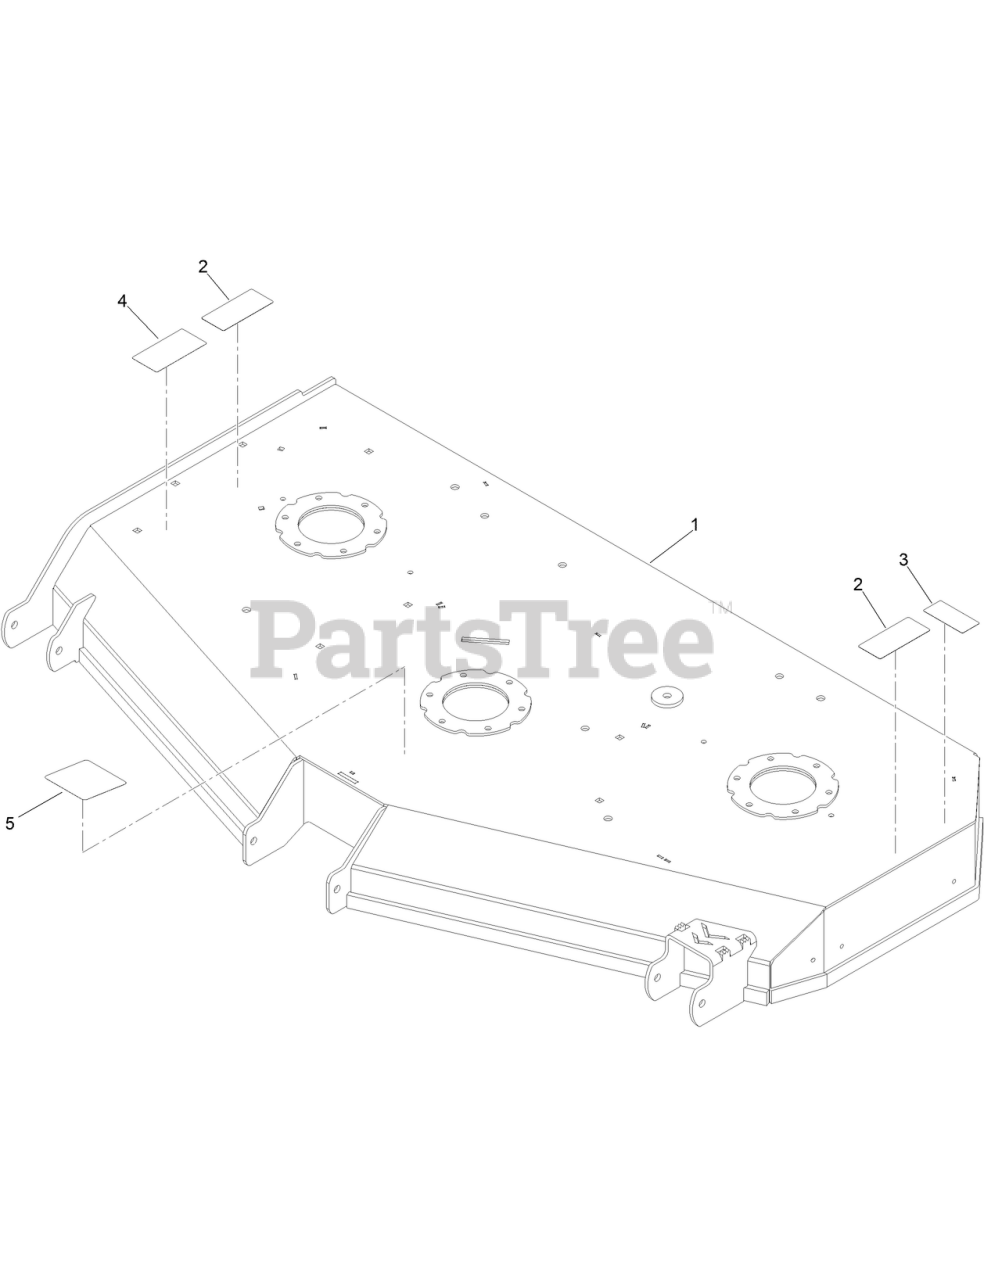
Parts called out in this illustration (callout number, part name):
1	DECK ASM-61 PAINTED BLACK
2	DECAL-ROTATING FAN HAZARD
3	DECAL-SAFETY BLADE TORQUE
4	DECAL-DANGER, DECK
5	DECAL-DECK BELT ROUTING
